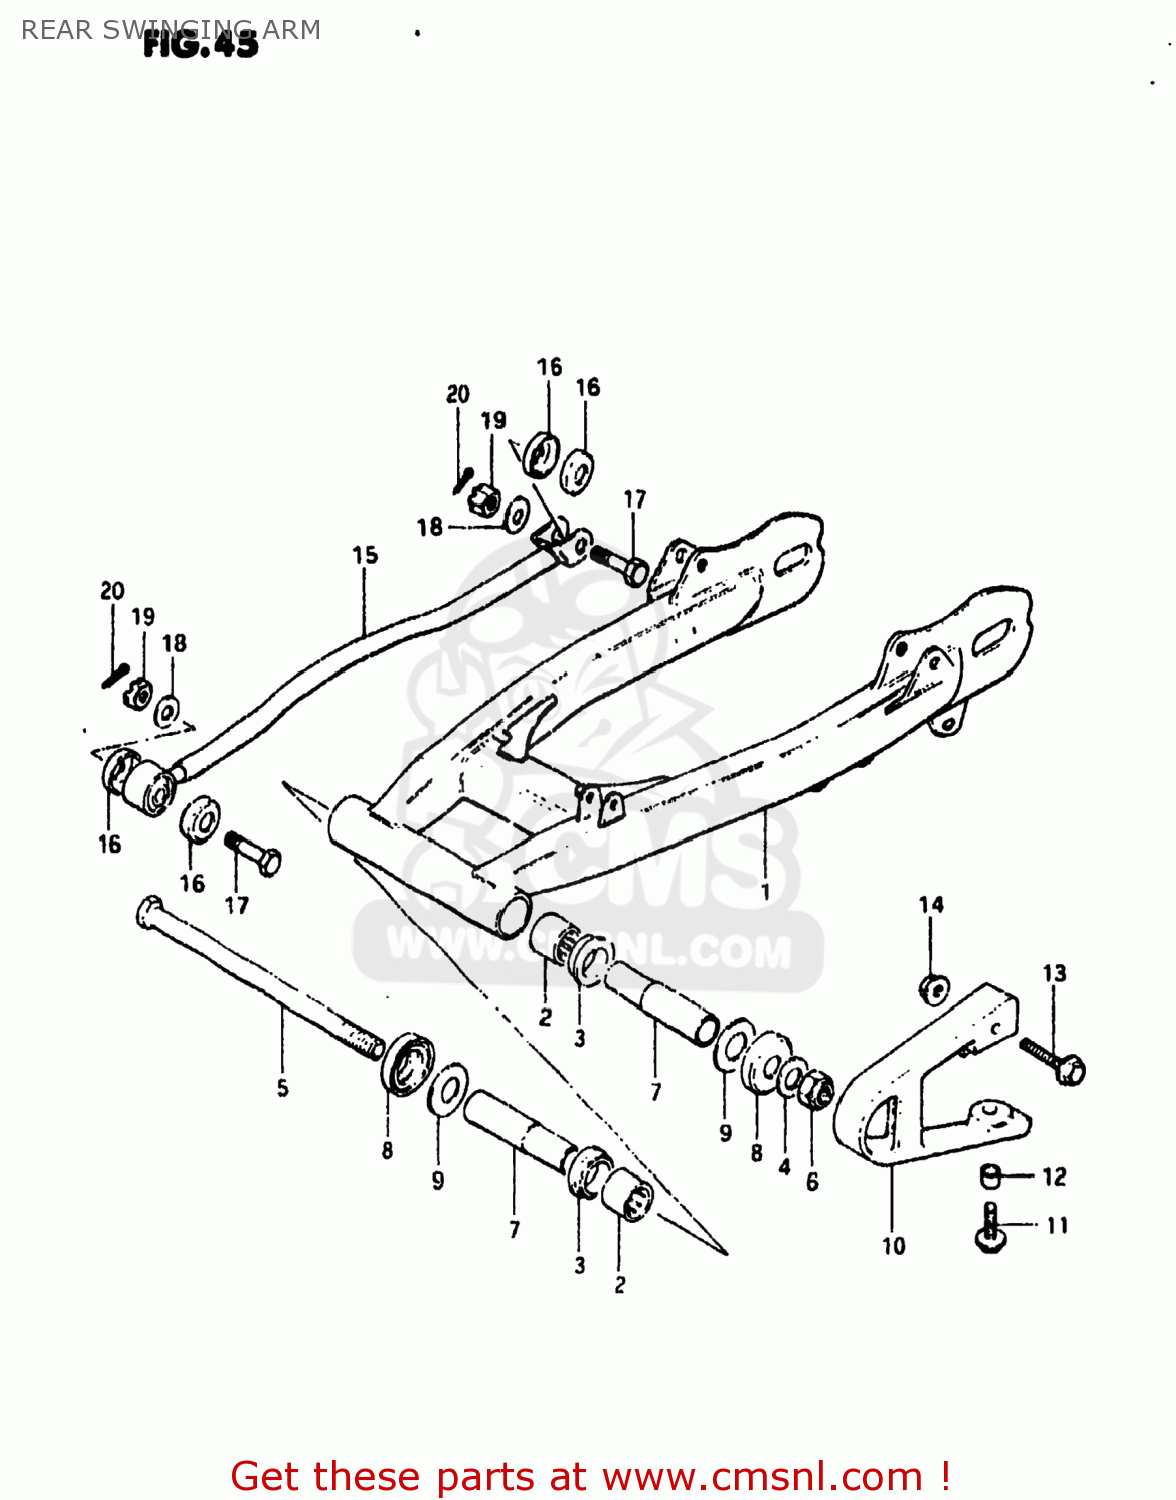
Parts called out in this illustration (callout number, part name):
1	SWING ARM ASSEMBLY,REAR
2	BEARING
3	BUSHING,REAR SWING ARM PIVOT
4	WASHER
5	SHAFT,REAR SWING ARM
6	NUT 16MM
7	SPACER,REAR SWING ARM
8	COVER,REAR SWING ARM DUST
10	BUFFER,CHAIN TOUCH DEFLECTOR
11	SCREW,CHAIN TOUCH DEFEND
12	SPACER (5.5X8X4)
13	BOLT,UNDER
14	NUT
15	TORQUE LINK,REAR
16	17
17	BOLT 8X28
18	WASHER
19	NUT 8MM
20	PIN 20X20
